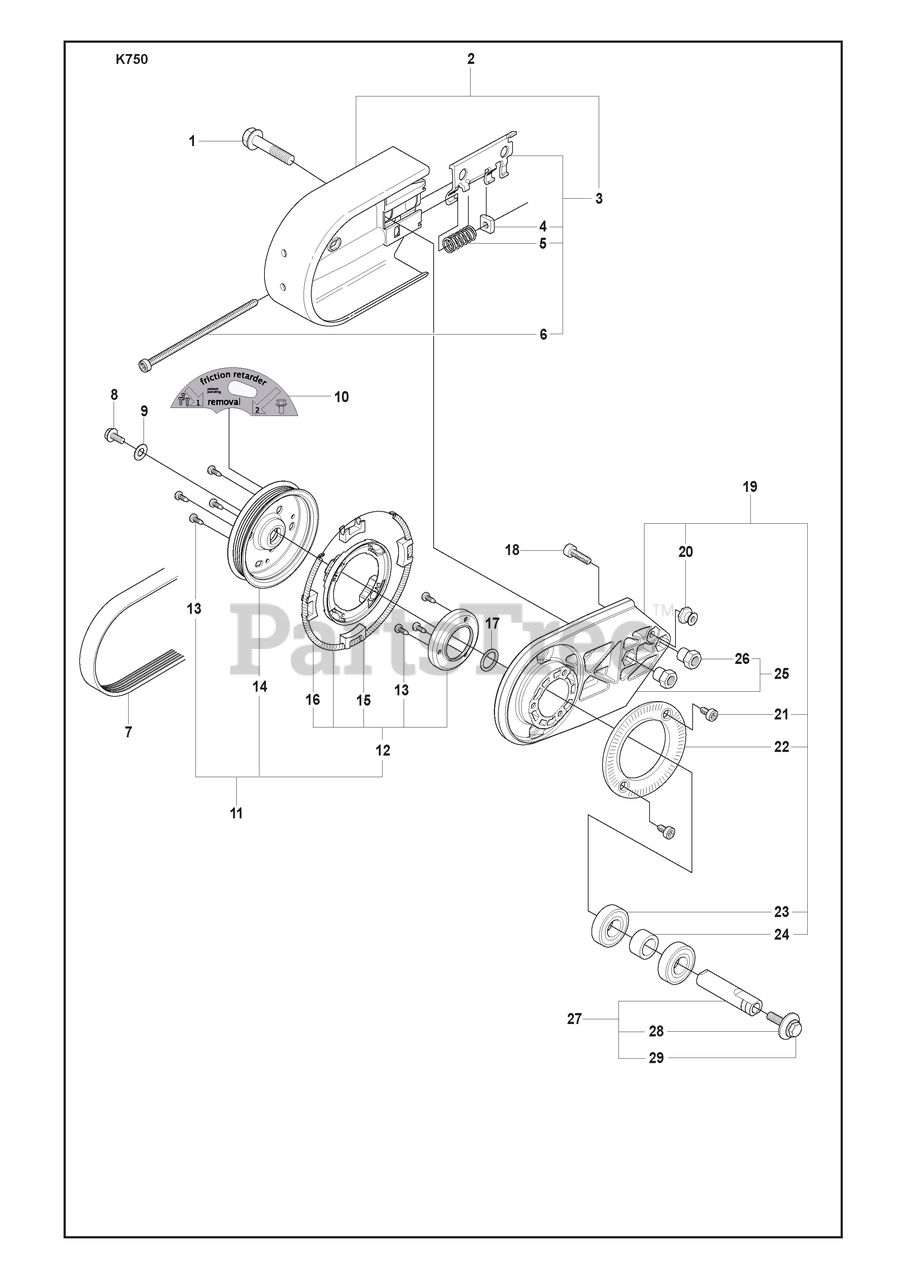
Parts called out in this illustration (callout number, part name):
1	BOLT
2	BELT GUARD
3	TENSIONER
11	PULLEY
12	PULLEY
14	%PULLEY
15	RP BRAKE SHOE
16	DRAW SPRING
17	WASHER 15X21
18	SCREW MC6S 5X16
19	HOUSING
23	BALL BEARING
25	HOUSING
27	SHAFT
28	WASHER
29	SCREW
